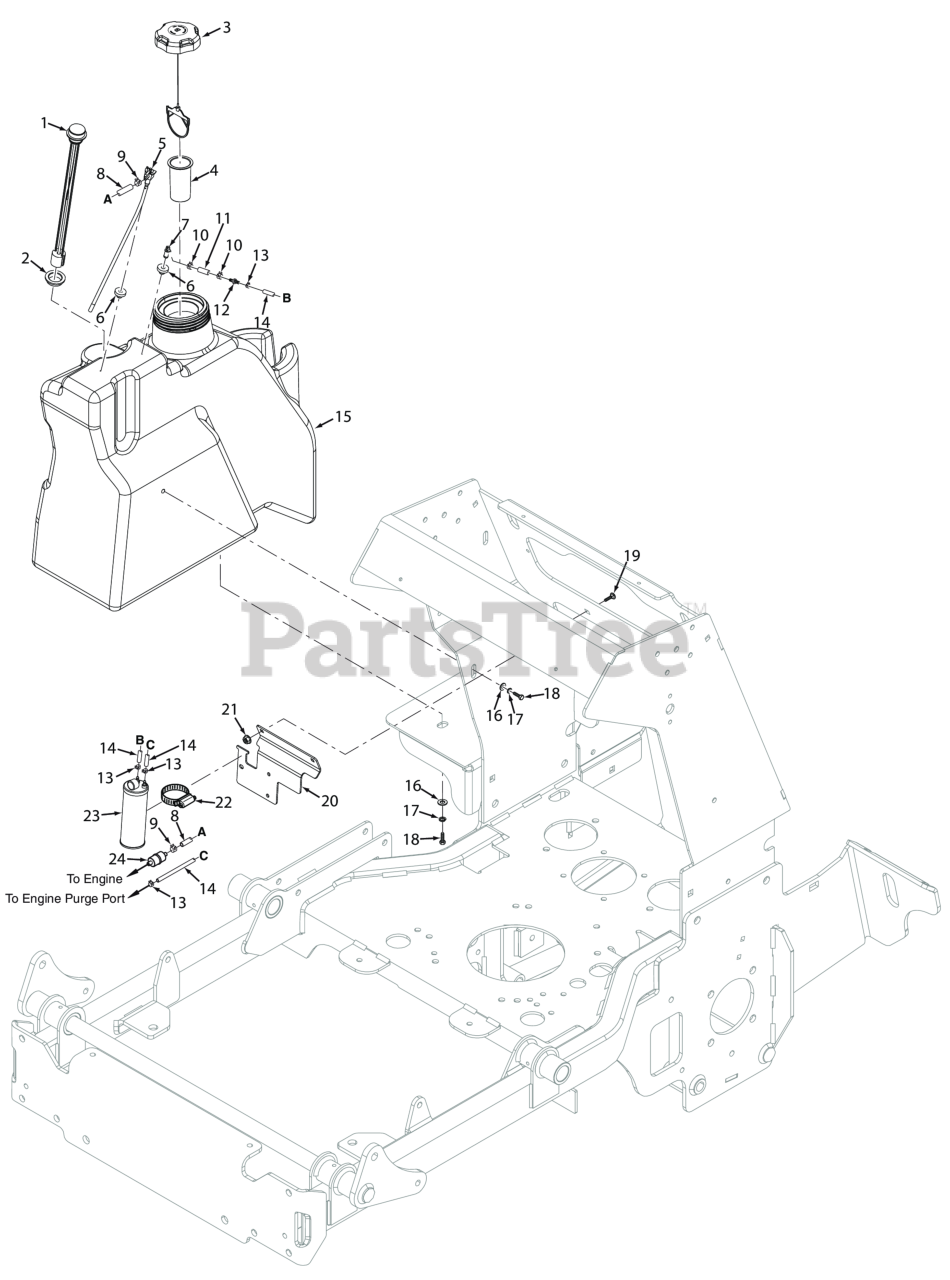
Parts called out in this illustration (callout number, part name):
1	Fuel Gauge Assy., 14.6" (32)
2	Grommet, Fuel Gauge
3	Fuel Cap w/ Tether (E.P.A.)
3	Fuel Cap, Tethered - CA models only
4	Tube, Fuel Tank Insert - 4"
5	Valve, Fuel Shutoff (32)
6	Bushing, 0.56" Dia. Viton
7	Remote Vent
8	Fuel Hose, 1/4" I.D. Non-Perm (791DFI Fuel Return) - Order by Inch
9	Clamp, Fuel Hose 1/4" Hose I.D.
10	CLAMP, FUEL HOSE(KAWASAKI ONLY)
11	Hose, 1/4" Vapor Recovery (order by inch)
12	Mender, 1/4 x 3/16 w/0.02 Hole
13	Clamp, Vapor Recovery Hose 3/16"
14	Hose, Vapor Recovery 3/16" (order by inch)
15	Fuel Tank Assy., SVRII-32
16	Flatwasher, 5/16-.375 x .875 x .083 (35BV & 37BV-EFI)
17	Lockwasher, 5/16 (.317 x .586 x .078) Helical Spring
18	BOLT, SERRATED FLANGE HEX HEAD 5/16-18 X 3/4"
19	Bolt, 5/16-18 x .75 RHSN Carriage
20	Bracket, Hydro Tank Mounting
21	Nut, Serrated Flange 5/16-18 (Right Front Engine Mounting, Briggs and Kohler Only)
22	Clamp, 3-1/2" Max. Dia.
23	Carbon Canister - SVR-52V / SVR-61V
23	Dust Filter, Carbon Canister
24	Fuel Filter
